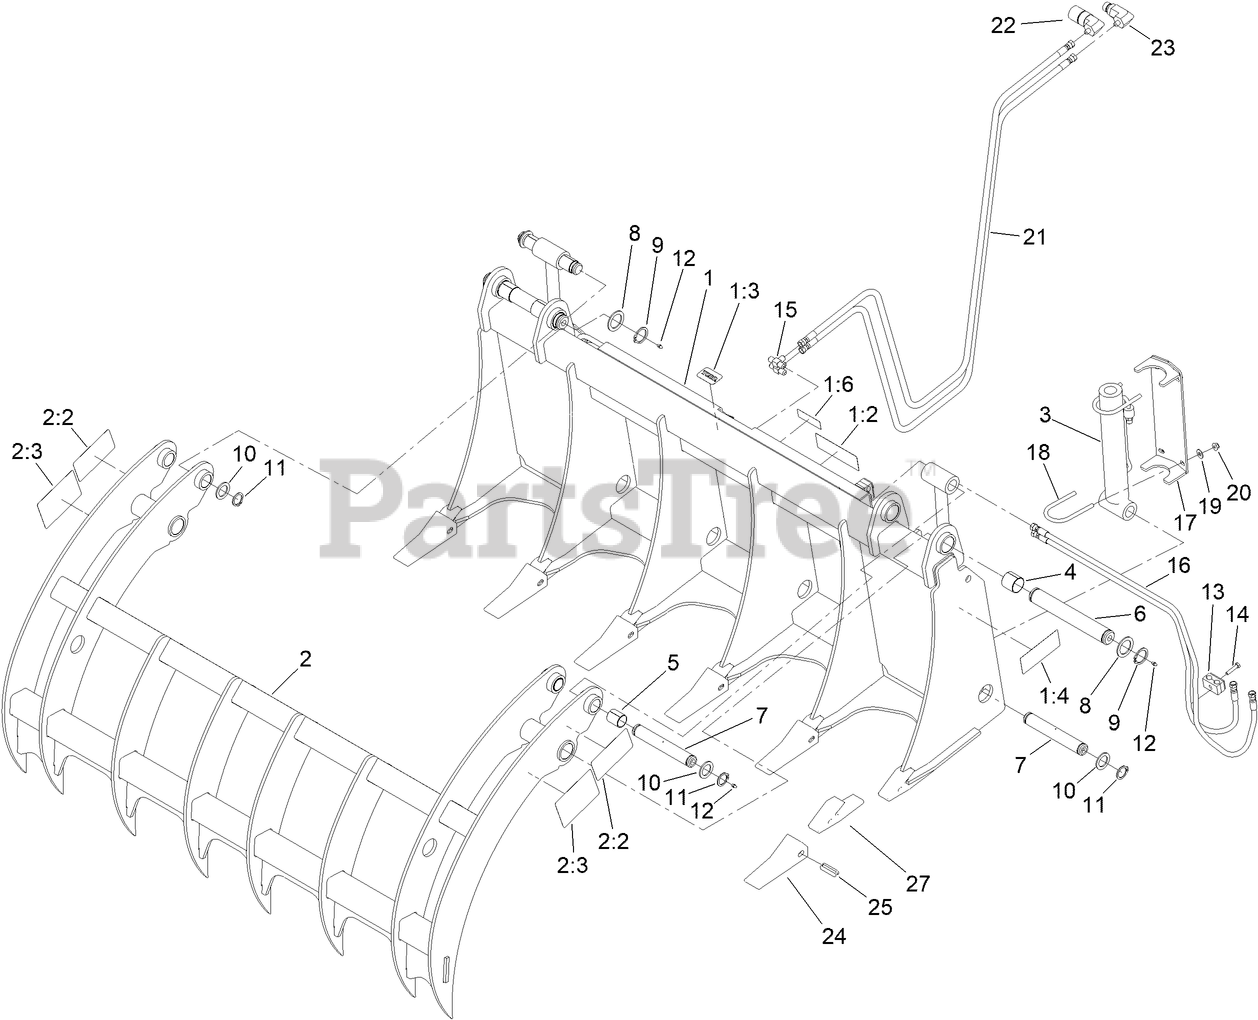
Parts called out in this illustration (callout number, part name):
1	BUCKET FRAME ASM
1:2	DECAL-CAPACITY
1:3	DECAL
1:4	DECAL-WARNING
2	JAW ASM
2:2	DECAL-DANGER, CRUSH
2:3	DECAL-DANGER, GRAPPLE
3	HYDRAULIC CYLINDER ASM
4	BUSHING
5	BUSHING
6	PIN-HINGE
7	PIN-PIVOT
8	WASHER
9	RING-SNAP, EXTERNAL
10	WASHER
11	RING-RETAINING, EXTERNAL
12	FITTING-ZERK
13	CLAMP-HOSE
14	SCREW-HH
15	FITTING-TEE
16	HOSE-HYD
17	GUARD-CYLINDER
18	U-LINK
19	WASHER-FLAT
20	NUT-HF, NI
21	HOSE-HYD
22	FITTING-ELBOW
23	FITTING-ELBOW
24	TOOTH-CAST
25	PIN-FLEX
27	SHANK-TOOTH, WELD-ON
